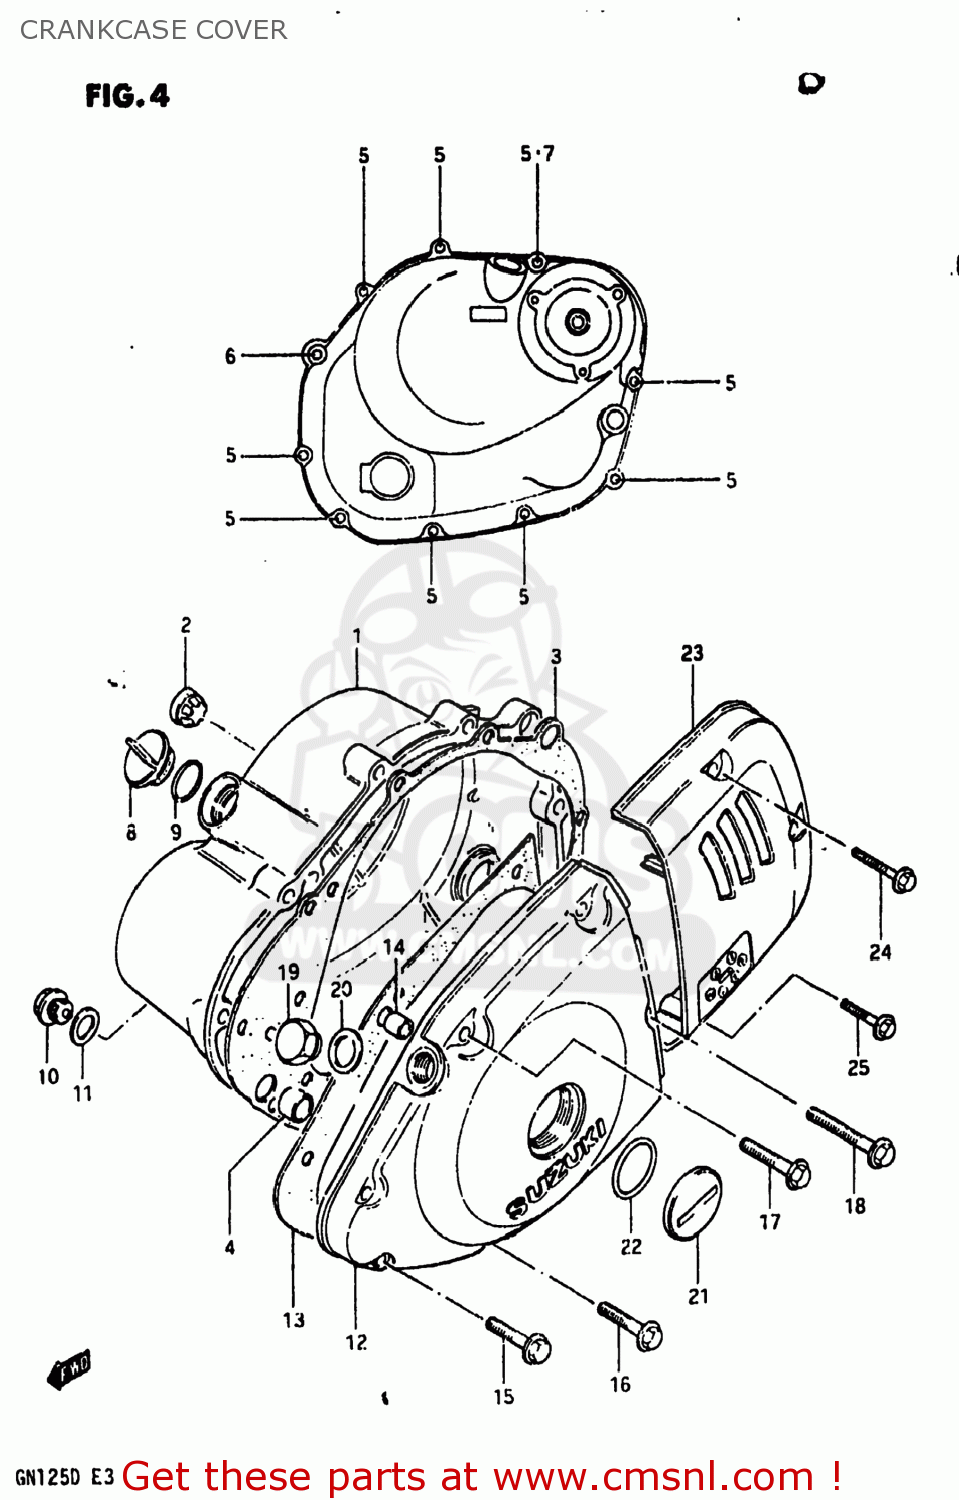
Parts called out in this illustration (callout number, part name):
1	COVER,CLUTCH
2	LENS,OIL LEVEL CHECK
3	GASKET,CLUTCH COVER (MCA)
4	PIN
5	BOLT (6X30)
6	BOLT
7	WASHER
8	PLUG
9	O RING(D:3.1,ID:16.8)
10	PLUG (14X12)
11	GASKET(14X19.2X2) (NAS)
12	COVER,MAGNETO
13	GASKET,MAGNETO COVER (MCA)
14	PIN
15	BOLT (6X30)
16	BOLT (6X35)
17	BOLT (6X40)
18	BOLT (6X50)
19	PLUG,12X9
20	GASKET(12.1X16.2X3.7) (NAS)
21	PLUG
22	O RING(D:3.1,ID:22.7)
23	COVER,SPROCKET
24	BOLT
25	BOUT
